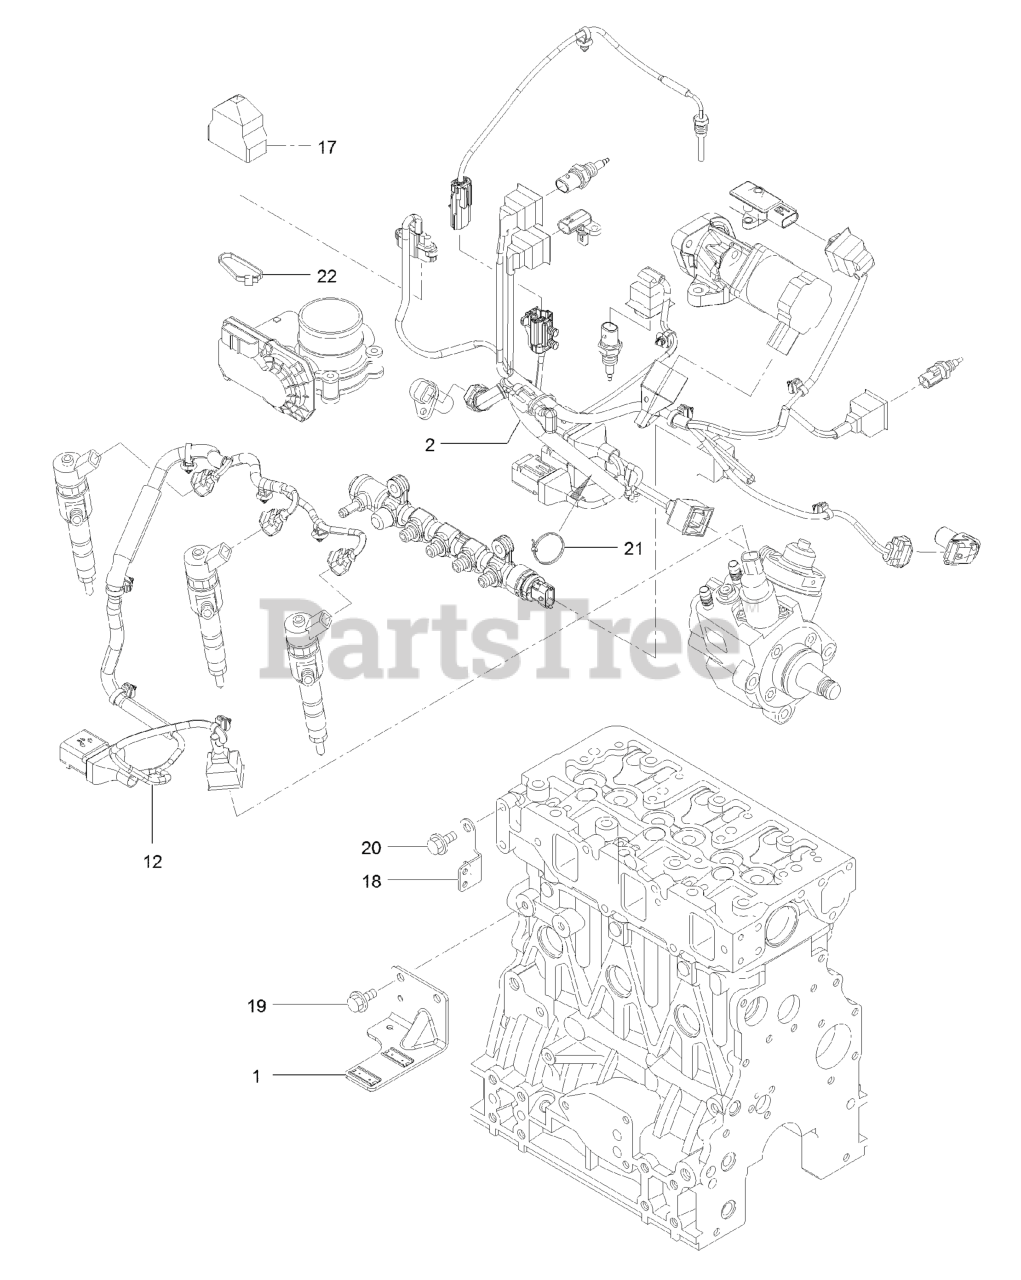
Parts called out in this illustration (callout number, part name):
1	BRACKET-CONNECTOR
2	HARNESS
12	HARNESS
17	Boot-Cap
18	Bracket-Harness
